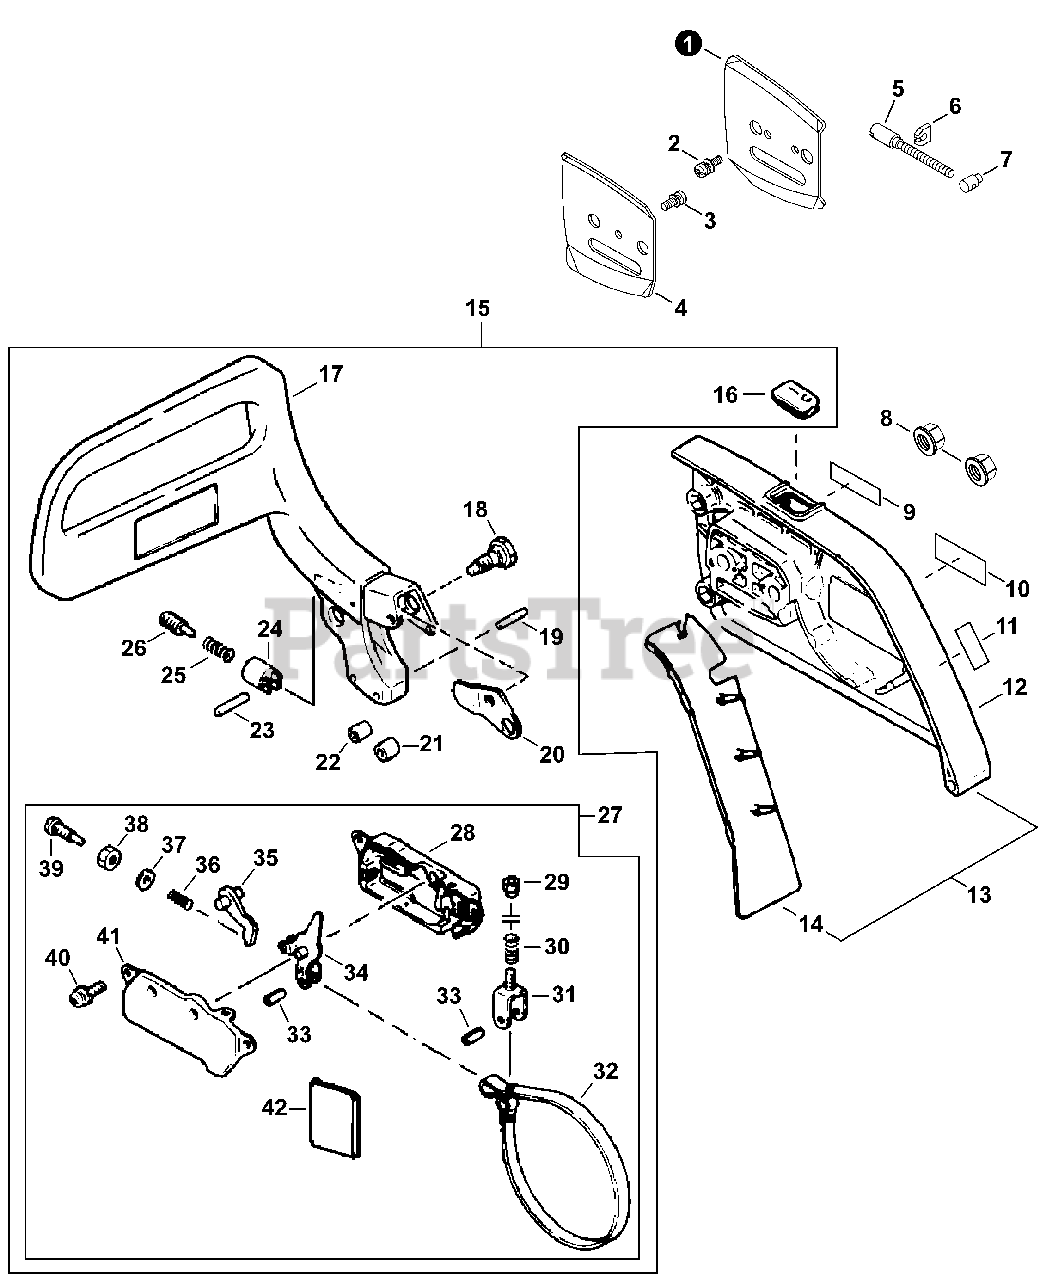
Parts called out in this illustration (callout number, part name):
1	PLATE, GUIDE - OUTER
2	SCREW 3x6
3	SCREW 4x8
4	PLATE, GUIDE - INNER
5	SCREW, ADJUSTER
7	TENSIONER, CHAIN
8	NUT, FLANGE M8x1.25
9	LABEL - WARNING
10	LABEL - ECHO
11	LABEL - OILER
12	GUARD, SPROCKET - ORANGE
13	GUARD SET, SPROCKET - GRAY
15	BRAKE ASSY, CHAIN - ORANGE
15	BRAKE ASSY, CHAIN - BLACK
17	LEVER, BRAKE - ORANGE
17	LEVER, BRAKE - BLACK
19	PIN 3x18
22	SPACER
23	PIN 2x20
27	BRAKE ASSY, CHAIN
28	COVER, BRAKE
31	ADJUSTER, BRAKE BAND
32	BAND, BRAKE
33	PIN, SPRING 4x10
34	LEVER, BRAKE
35	STOPPER, BRAKE
36	SPRING ,BRAKE
40	BOLT 4x10
42	SEAL, DUST
